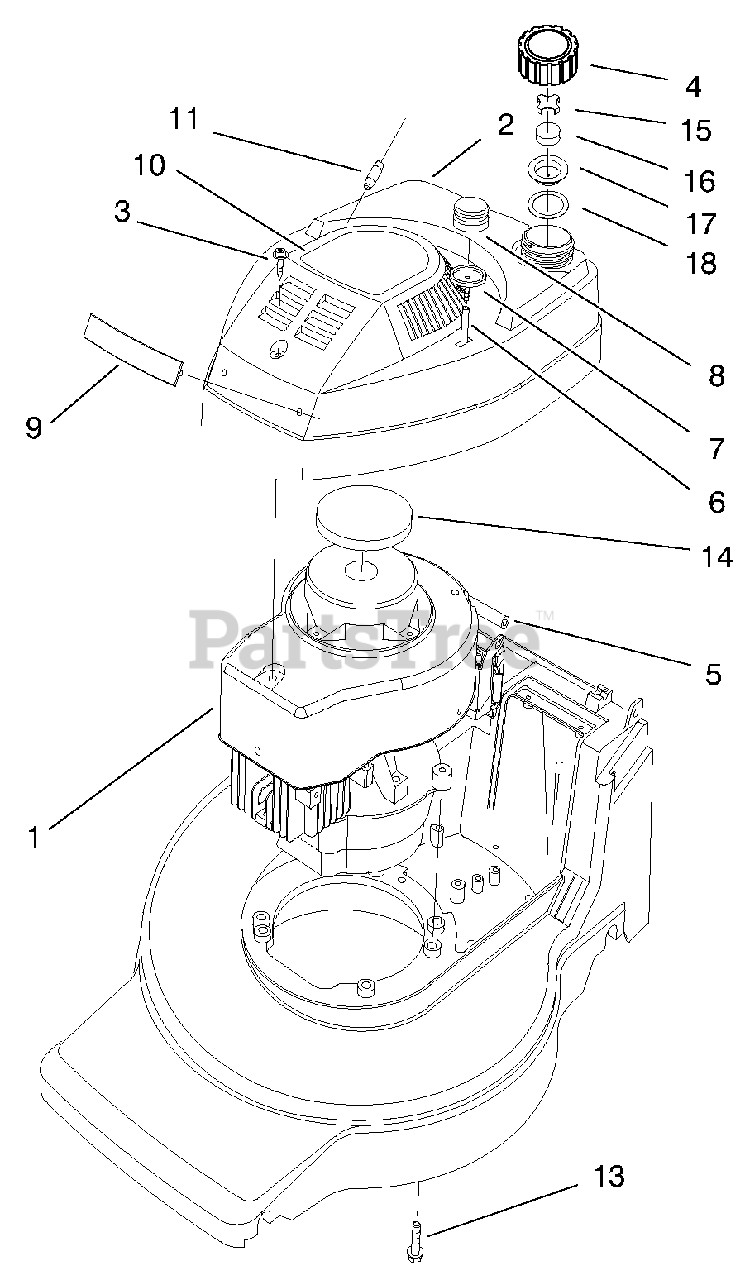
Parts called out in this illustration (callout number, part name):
1	Engine ASM
2	SHROUD & TANK ASM
4	ASM-Fuel/Oil Cap
5	LINE-FUEL
6	HOSE-PRIMER
7	BODY-PRIMER
8	BULB-PRIMER
9	APPLIQUE-SHROUD
10	DECAL - RECOIL
11	STOP-ROPE
13	SCREW-HWH
14	DISC - FOAM
15	BAFFLE - GAS CAP
16	BAFFLE - FOAM SM
17	COVER-FUEL CAP BAFFLE
18	GASKET-FUELCAP SM
